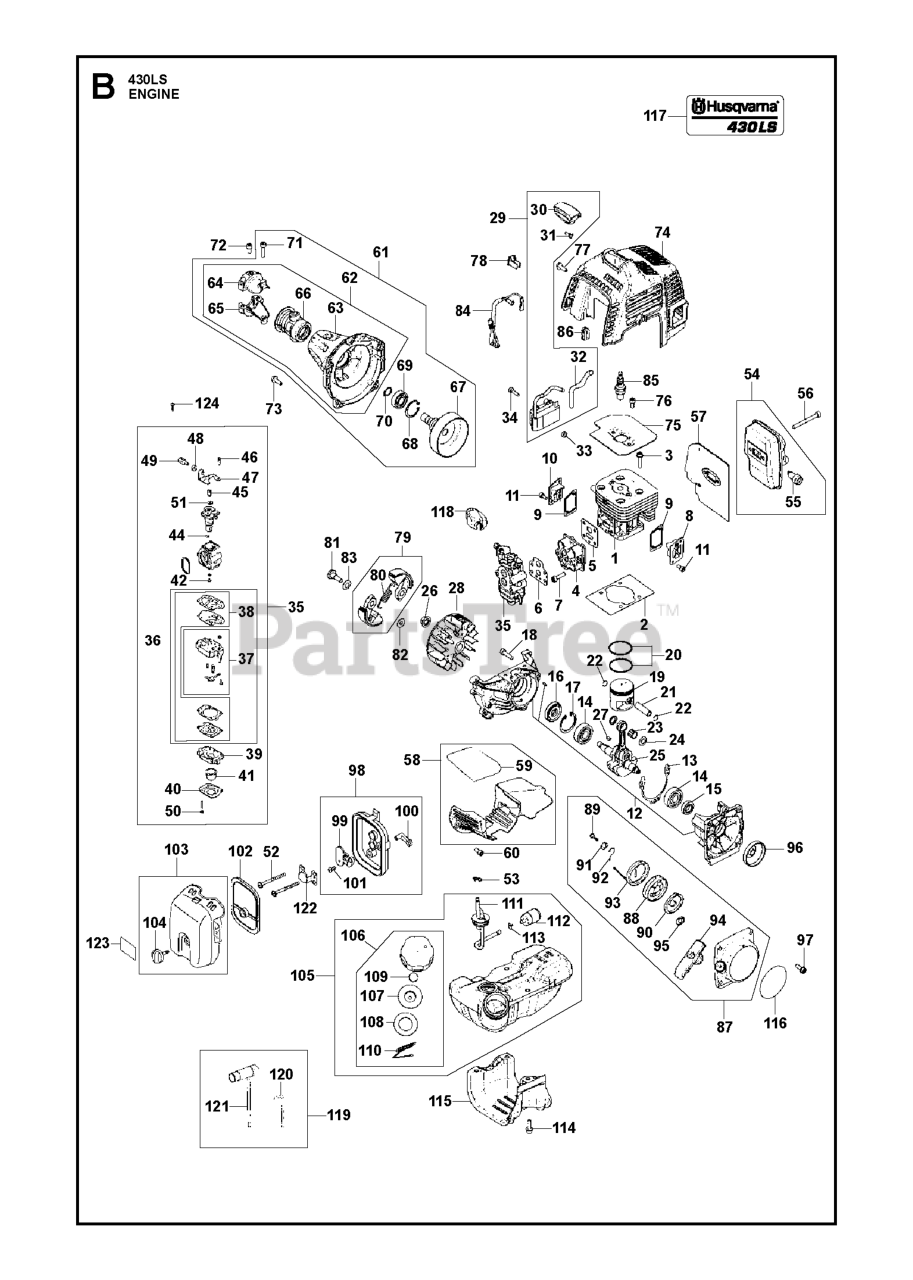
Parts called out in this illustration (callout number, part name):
2	GASKET BASE
5	GASKET, INSULATOR
6	GASKET, CARB (RPLS T155113131)
7	BOLT, TORX
8	COVER, TRS
9	GASKET, TR
10	COVER,TRF (RPLS 848F6012D1)
12	CRANKCASE-C
13	GASKET CASE
18	BOLT
25	CRANKSHAFT-C
26	NUT
31	SPRING
35	CARBURETOR A WYA-125
36	REBUILD KIT
37	CARBURETOR BODY
38	GASKET KIT
48	NUT
49	SCREW CABLE ADJUST
60	BOLT 08
61	HOUSING ASSY
62	HOUSING COMP.
64	BRACKET (A) (RPLS T170031211)
65	BRACKET (B)
67	DRUM (RPLS 481031120-22)
71	BOLT
75	RP_PLATE
76	BOLT 08
85	SPARK PLUG CMR7H-10
87	RECOIL ASSY
90	SPRING, SPIRAL
95	PLATE.STOPPER
98	CLEANER BODY ASSY
99	PLATE, CHOKE
102	ELEMENT
103	COVER ASSY
105	Tank Evp Assembly
111	PIPE-C
112	FILTER
115	GUARD, TANK
119	TOOL SET (RPLS 848-8UD-0120)
121	SOCKET
